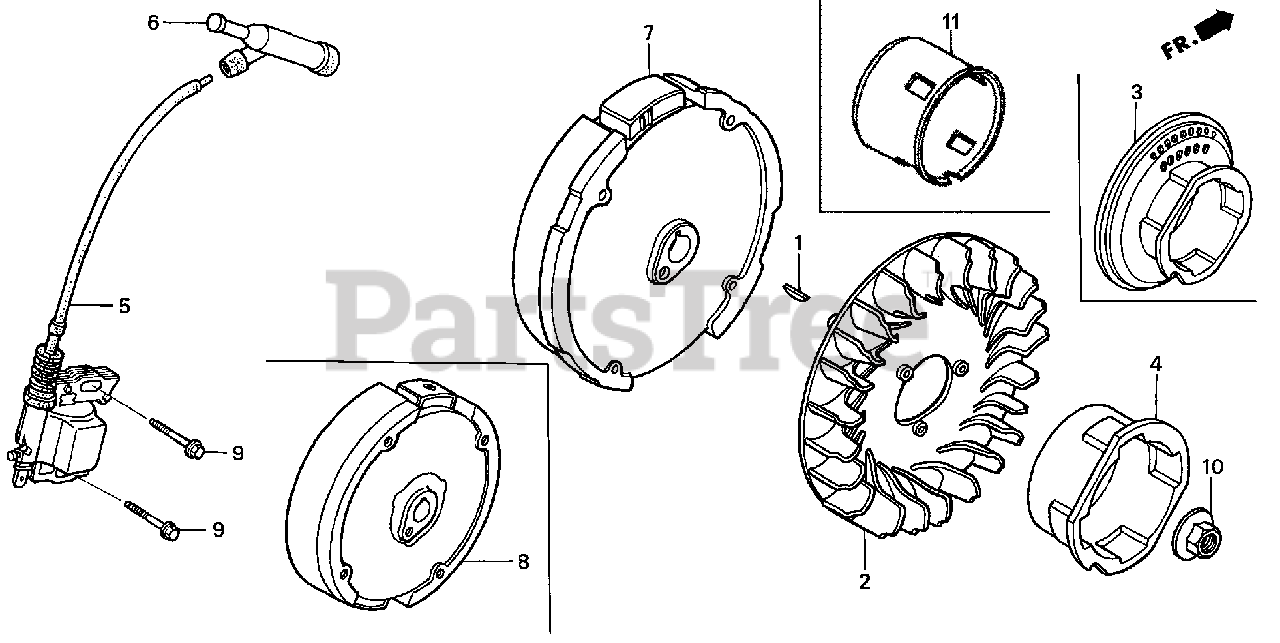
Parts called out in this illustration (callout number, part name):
1	KEY, SPECIAL WOODRUFF (25X18)
2	FAN, COOLING
4	PULLEY, STARTER
5	COIL ASSY., IGNITION
6	CAP ASSY., NOISE SUPPRESSOR (NICHIWA Y-EZ RTFM256)
8	FLYWHEEL (STD)
9	BOLT, FLANGE (6X25) (CT200)
10	NUT, SPECIAL (14MM)
11	PULLEY, STARTER
